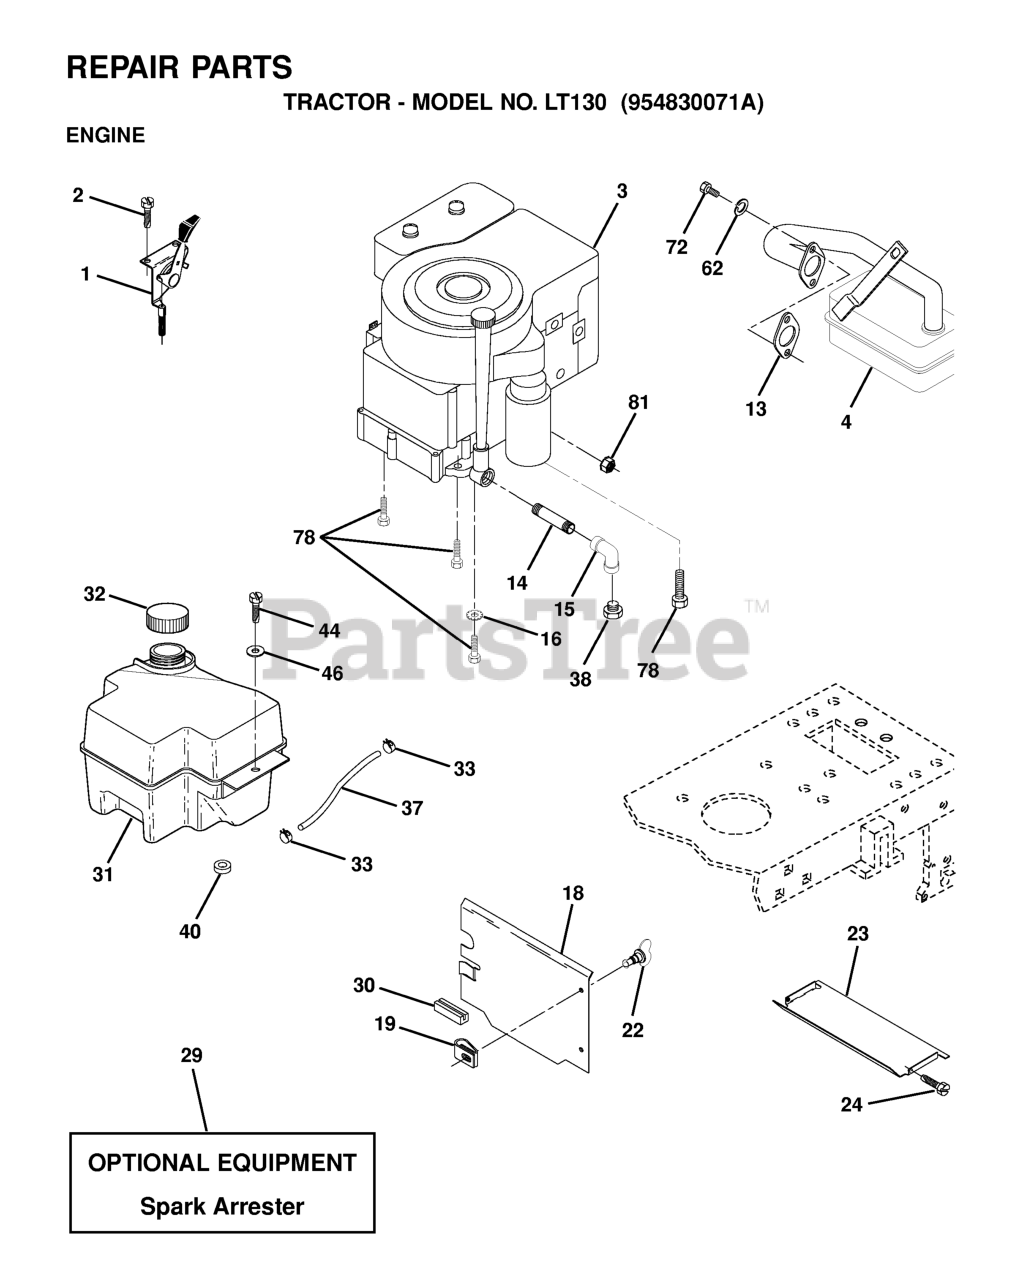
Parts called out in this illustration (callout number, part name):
1	CHOKE CONTROL
2	SCREW LT
4	MUFFLER.SINGLE.B&S.10-12HP
13	GASKET.ENG.1.313 ID.TIN PLATED
14	Nipple Pipe 3/8 Npt X 3-1/2
15	ELBOW
16	LOCKWASHER
18	HEAT SHIELD
19	RECEPTACLE LT
20	RETAINER LT
22	STUD 1/4 TURN
23	HEAT SHIELD
29	KIT.SPARK ARRESTOR 794945 B&S
31	FUEL TANK
32	FUEL CAP
33	HOSE CLAMP
37	LINE.FUEL.20
40	BUSHING.SNAP.NYL.BLK.
44	SCREW HEX CRT
62	WASHER.LOCK.HVY.HLCL.SPR.5/16
72	SCREW
78	SCREW
81	NUT FLANGE 1/4-20 STARTER NUT
